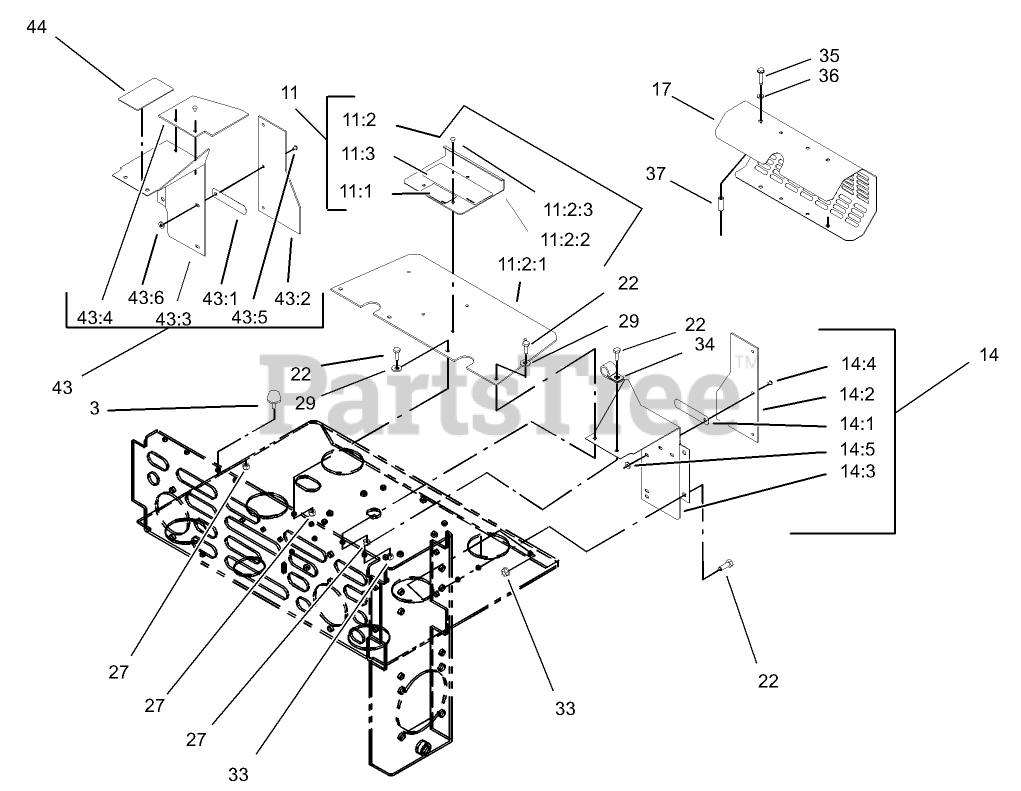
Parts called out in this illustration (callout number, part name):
3	BUMPER
11	SHIELD ASM
11:1	DECAL-IMPORTANT
11:2	SHIELD AND LIFT ASM
11:2:1	SHIELD-ENGINE
11:2:2	LIFT-SHIELD
11:2:3	RIVET-POP
11:3	DECAL-DEVICES, ROTATING
14	LH SHIELD ASM
14:1	CLIP-BAFFLE, REAR
14:2	SHIELD-ENGINE
14:3	BAFFLE-ENGINE SHIELD, LH
14:4	RIVET-POP
14:5	WASHER-FLAT
17	GUARD-MUFFLER
22	SCREW-HH
27	NUT-LOCK, NI
29	WASHER-FLAT
33	NUT-HF
34	CLIP-LOOM
36	WASHER-SPRING
37	SPACER
43	RH SHIELD ASM
43:1	CLIP-BAFFLE, REAR
43:2	SHIELD-ENGINE
43:3	SHIELD-RH
43:4	BAFFLE-COOLER, ENGINE
43:5	RIVET-POP
43:6	WASHER-FLAT
44	DECAL-ROUTING, BELT
